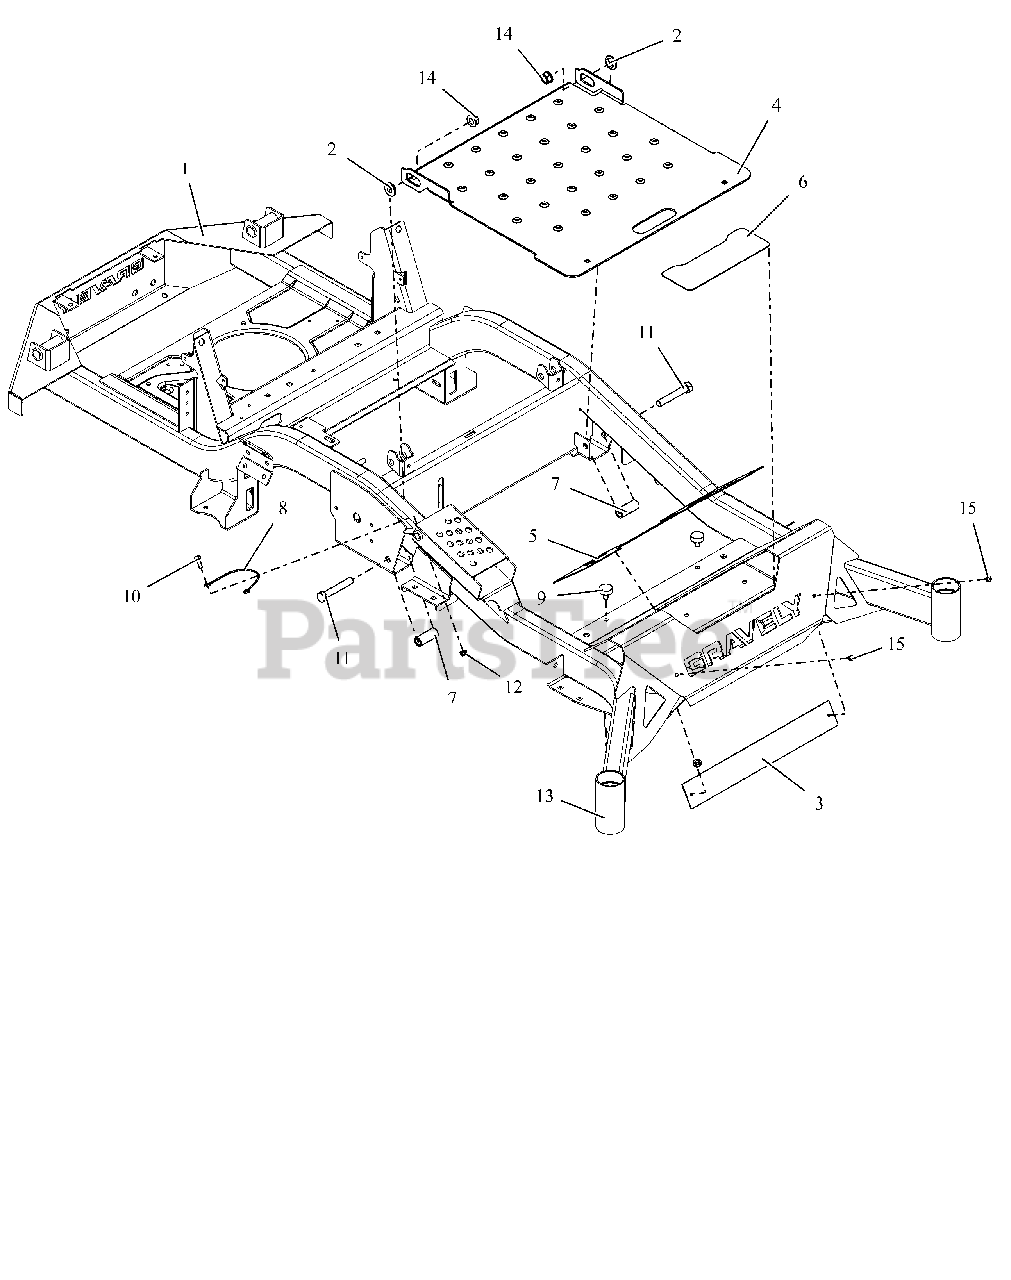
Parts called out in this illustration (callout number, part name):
1	HD 60"FRAME W/SAFETY DECALS
2	BSHG-FLG .515X.750X.310X1.120
3	PLATE, BACK FOOT-REST XL
4	KIT,ACCESS PANEL W/DECALS-RED
5	GRIP, FRONT
6	GRIP, STEP
7	SPACER, .515X.75X1.83
8	CABLE, 12.0 LANYARD, NYLON
9	BUMPER, RUBBER
10	BLT, HEX .25-20X.75 G5 ZCC
11	BLT, HEX .50-13X3.00 G5 ZCC
12	NUT,NYL-FLG .25-20 GF ZCC
13	NUT,SPNLK-FLG .31-18 G5 ZCC
14	NUT-LK-TOP-FLG .500-13 GF ZCC
15	RIVET, .1875 AL/AL .126-.250
